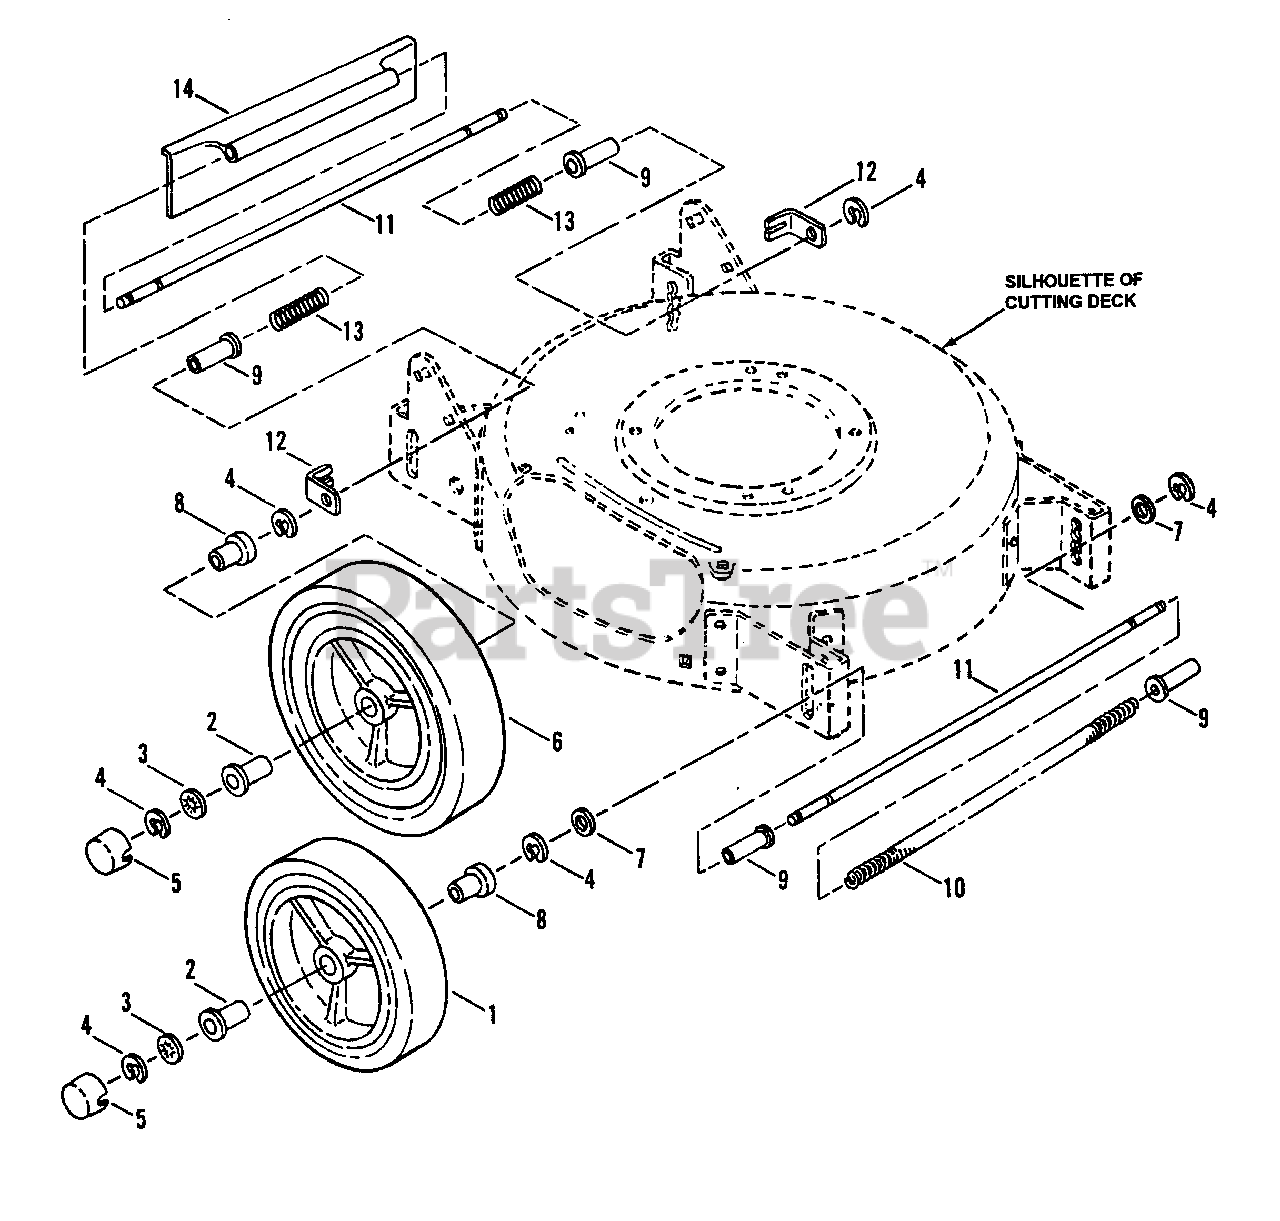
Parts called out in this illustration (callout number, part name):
1	WHEEL, Front, 7 x 1.75 Ball Bearing
2	BUSHING, Wheel
3	RETAINER, Push-On
4	RING, Retaining
5	HUB-CAP
6	WHEEL, Rear, 8 x 2.00 Ball Bearing
7	WASHER, 3/8" Flat
8	BUSHING, Wheel
9	BUSHING, Height Adjustment
10	SPRING, Front Axle
11	AXLE, 3/8 x 10 3/8"
12	CLIP, Rear Foot Guard
13	SPRING, Rear Foot Guard
14	GUARD, Rear Foot
